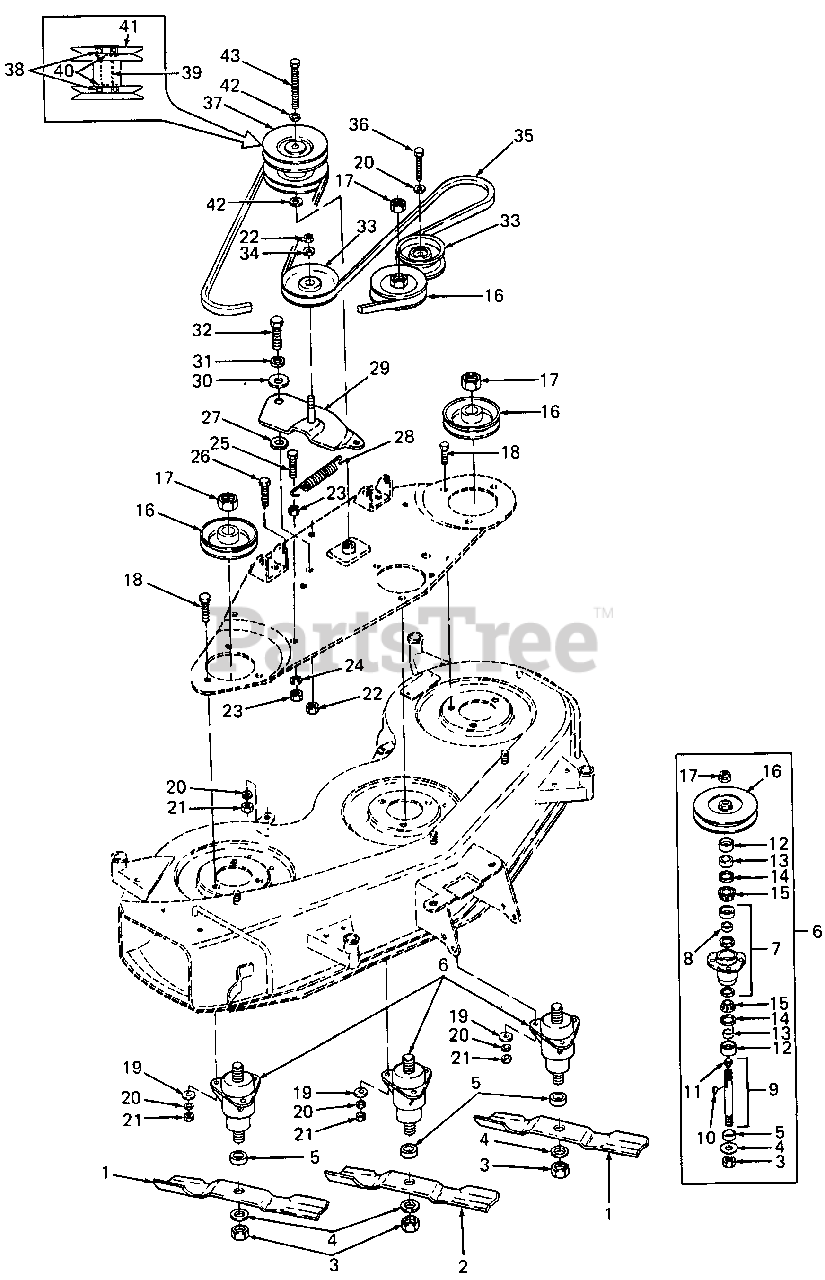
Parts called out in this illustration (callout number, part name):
1	Blade, Low Lift, 16.28 Lg
2	Blade, Low Lift, 14.88 Lg
3	Nut, Hex, 3/4-16 GR8
4	Washer, Flat, .781 X 2.0 X .105 Thk
5	Spacer, Blade
6	Spindle Service Kit
7	Housing, Spindle w/Cups
8	Spacer, Bearing
9	Kit, Shaft w/Seal
10	Key, #91 Woodruff, 1/4 X 3/4 HDN
11	Fitting, Lube, 3/16
12	Cup, Spindle HDN
13	Spacer, .755 X 1.25 X .44 Lg
14	Seal, Oil, 1.25 X 1.874 X .25
15	Cone, Bearing
16	4L V-Pulley, 4.62 OD X .75 ID
17	Nut, Hex Jam, 3/4-16
18	Screw, Hex Cap, 3/8-16 X 1.25 GR5
19	Washer, Flat, .378 X 1.0 X .127 Thk
20	Washer, Lock, 3/8 Dia
21	Nut, Hex, 3/8-16
22	Nut, Hex Center Lock, 3/8-16 GR5
23	Nut, Hex, 1/4-28
24	Washer, Lock, 1/4 Dia
25	Screw, Hex Cap, 1/4-28 X 1.25 Lg GR5
26	Screw, Hex Cap, 3/8-16 X 1.0 Lg GR5
27	Washer, Flat, .385 X .88 X .06 Thk HDN
28	Spring, Extension, .88 OD X 4.00 Lg
31	Washer, Bell, 3/8 Dia
32	Screw, Hex Cap, 3/8-16 X 1.25 Lg GR5
33	Idler, Flat, 3.5 OD
34	Washer, Flat, .406 X .75 X .63 Thk
35	V-Belt, 1/2 X 105.0 Lg
36	Screw, Hex Cap, 3/8-16 X 2.0 Lg GR5
37	Pulley Assy, Double
38	Bearing, Ball, .62 ID X 1.38 OD X .44 Thk
39	Spacer, Pulley, .64 ID X .81 OD X 2.25 Lg
40	Snap Ring, Internal
41	Pulley, Double
42	Washer, Flat, .63 ID X 1.0 OD X .63 Thk HDN
43	Bolt, Hex, 5/8-18 X 4.25 Lg GR5
